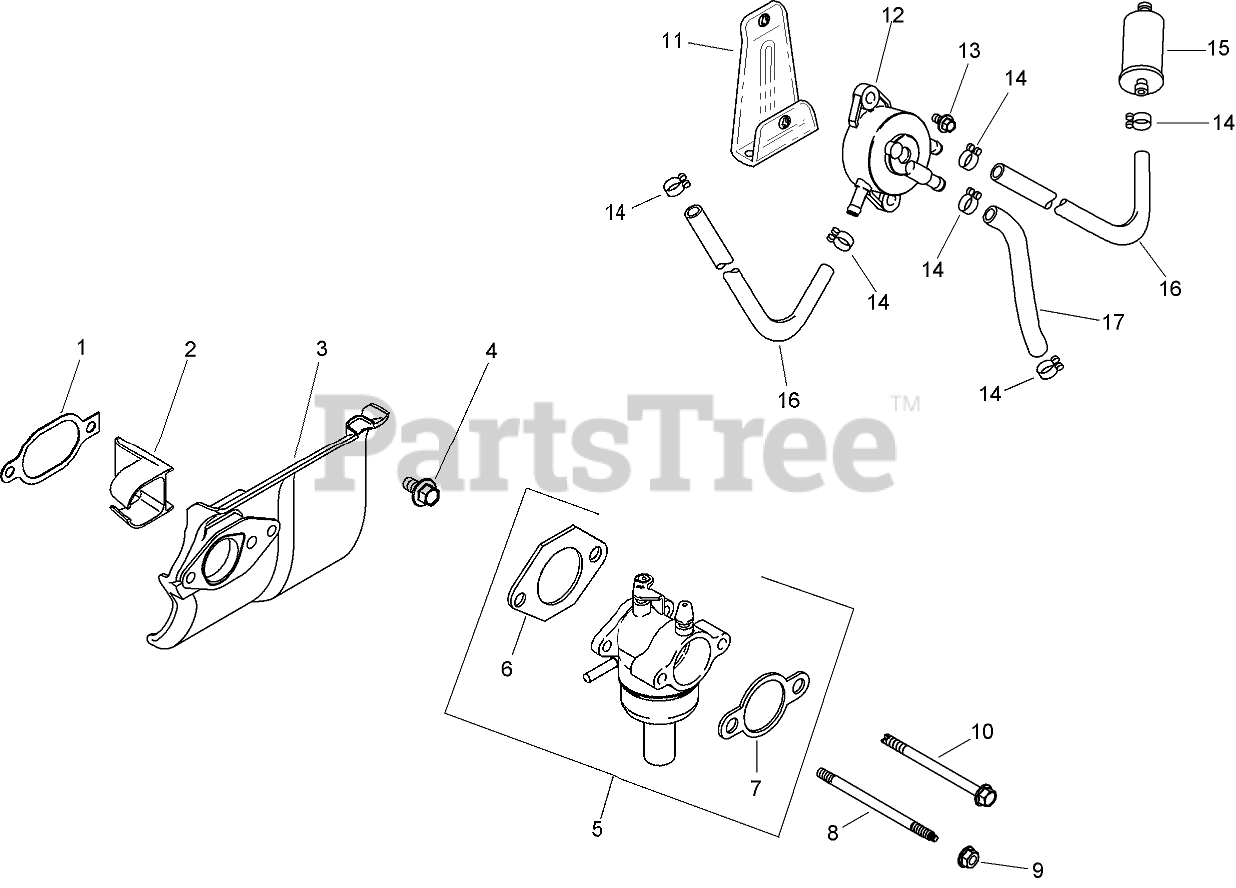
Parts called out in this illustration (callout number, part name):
1	Gasket-Deflector, Heat
2	INSERT-PORT, INTAKE
3	DEFLECTOR-HEAT
4	Screw-Flange, Hex (M6x1.0x20)
5	CARBURETOR ASM W/GASKETS (INCLUDES 6, 7)
6	Gasket-Carburetor
7	Gasket-Base, Air Cleaner
8	Stud-Mounting, Carburetor (M6X1.0X100)
9	NUT-FLANGE (M6X1.0)
10	SCREW-HHFTF (M5X.80X10)
11	BRACKET-MOUNTING, FUEL PUMP
12	PUMP-FUEL
13	SCREW-FLANGE, THREAD FORMING (M6X1.0X16)
14	CLAMP-HOSE, SPRING (1/2)
15	FILTER-FUEL
16	LINE-FUEL (24.0 CUT TO LENGTH)
17	Line-Fuel (10 Inch)
